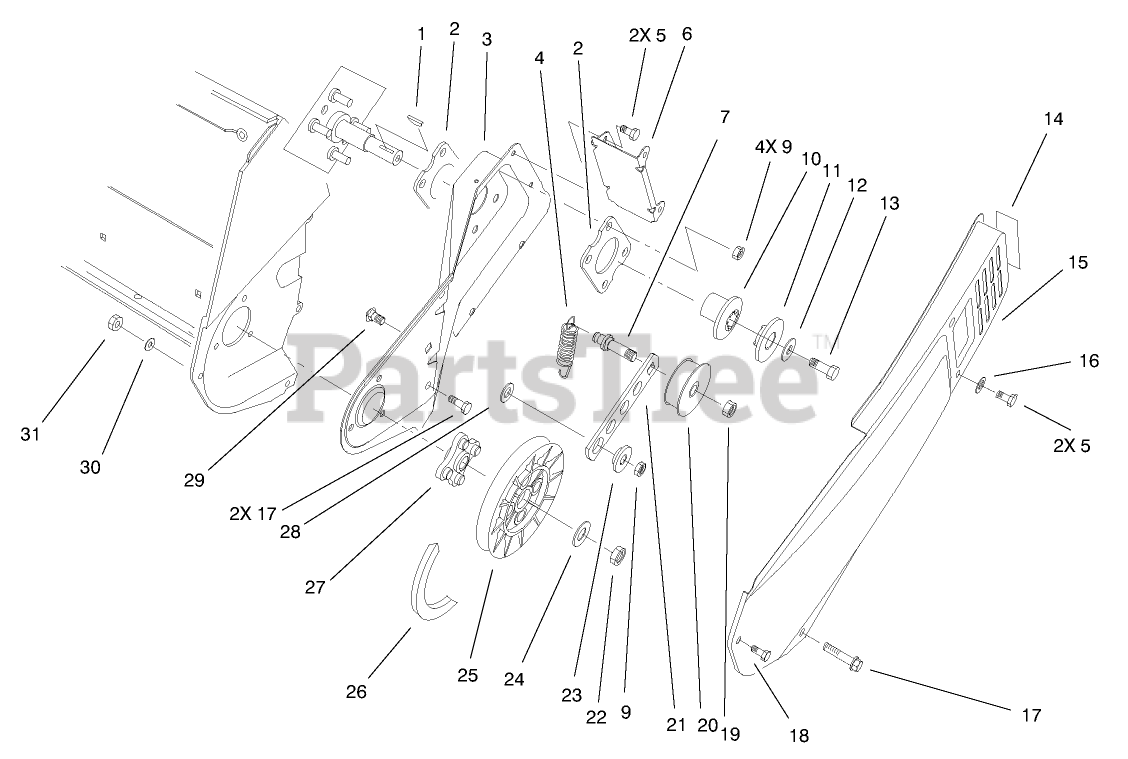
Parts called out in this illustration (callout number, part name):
1	KEY-WOODRUFF
2	PLATE-ENGINE
3	SIDEPLATE-LH
4	SPRING-EXTENSION
5	SCREW-HWH
6	BRACKET-COVER, BELT
7	PIN-IDLER
9	NUT-LOCK, NI
10	HUB-HALF SHEAVE
11	CAP-HALF SHEAVE
12	WASHER-FLAT
13	SCREW-HH
14	DECAL-WARNING
15	COVER-BELT
16	WASHER-FLAT
17	SCREW-PLASTIC
20	PULLEY-IDLER
21	ARM-IDLER
22	NUT-LOCK, NI
23	BUSHING-IDLER
24	WASHER-FLAT
25	PULLEY-DRIVEN
26	V-BELT
28	WASHER
29	SCREW-CARR
30	WASHER-FLAT
31	NUT-LOCK, NI
